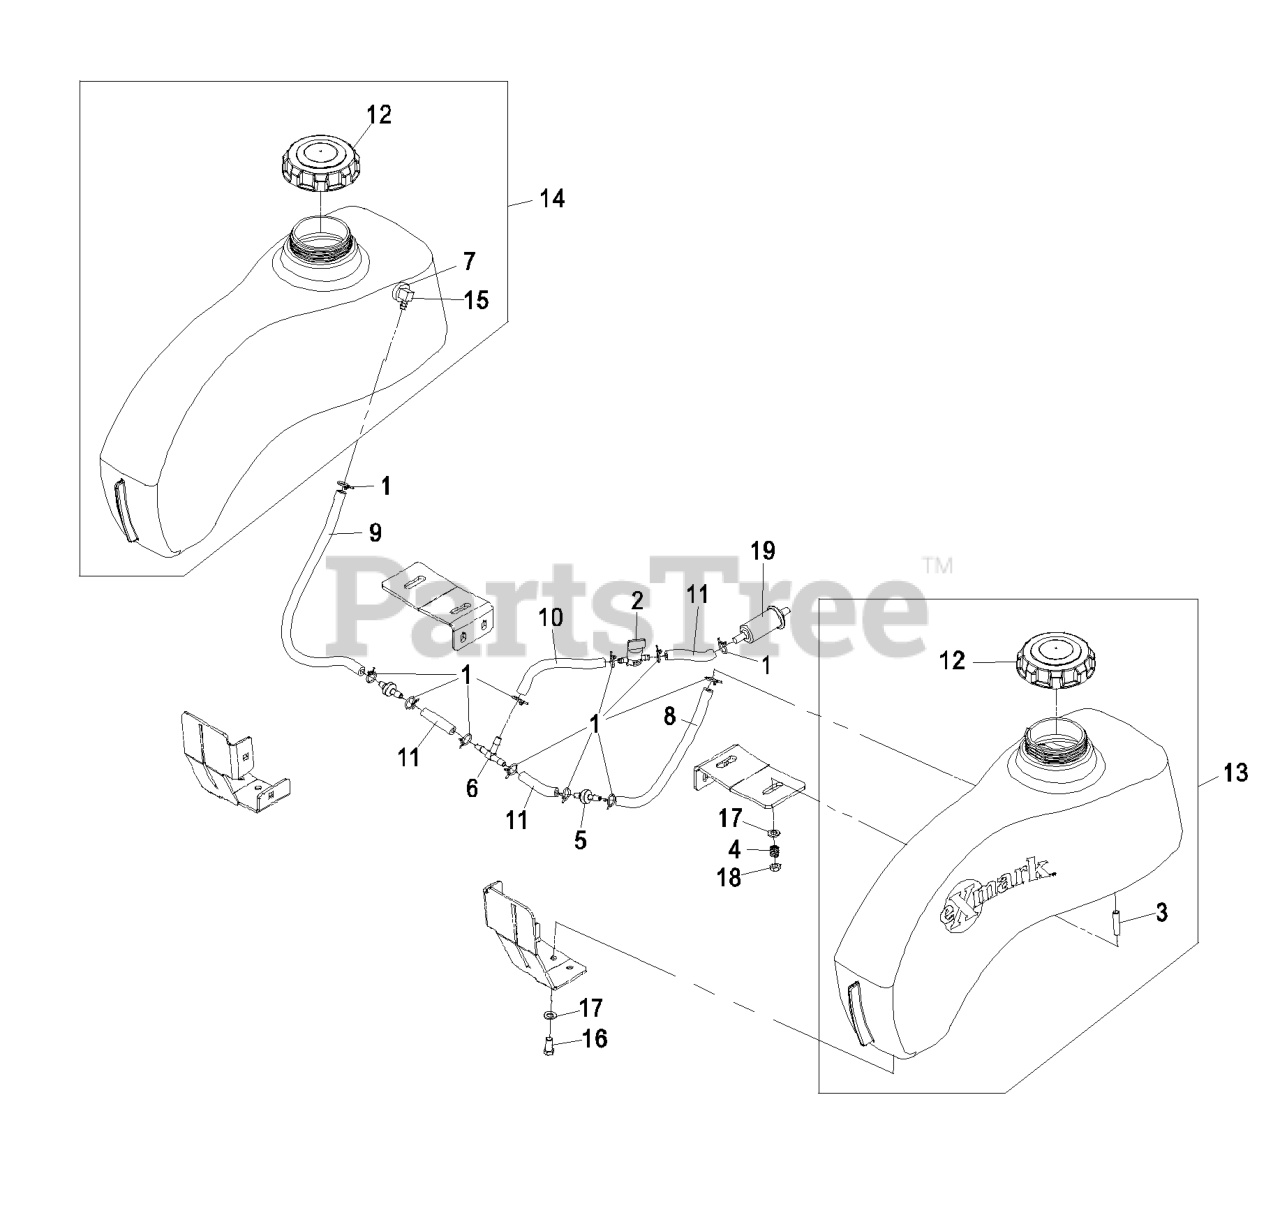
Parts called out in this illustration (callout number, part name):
2	VALVE-FUEL
3	STUD
4	SPRING-TANK, FUEL
5	VALVE-CHECK, FUEL
6	FITTING-TEE, BARBED
7	BUSHING
9	HOSE-FUEL
10	HOSE-FUEL
11	HOSE-FUEL
12	CAP-FUEL, GAS
13	ASM,LH PHAZER TANK W/STUD
14	ASM,PHAZER RH TANK W/STUD
15	FITTING-FUEL (W/LINE AND
16	SCREW-HH
17	WASHER-PLAIN
18	NUT-LOCK, NI
19	Kawasaki Part No. 49019-7001 Fuel Filter
